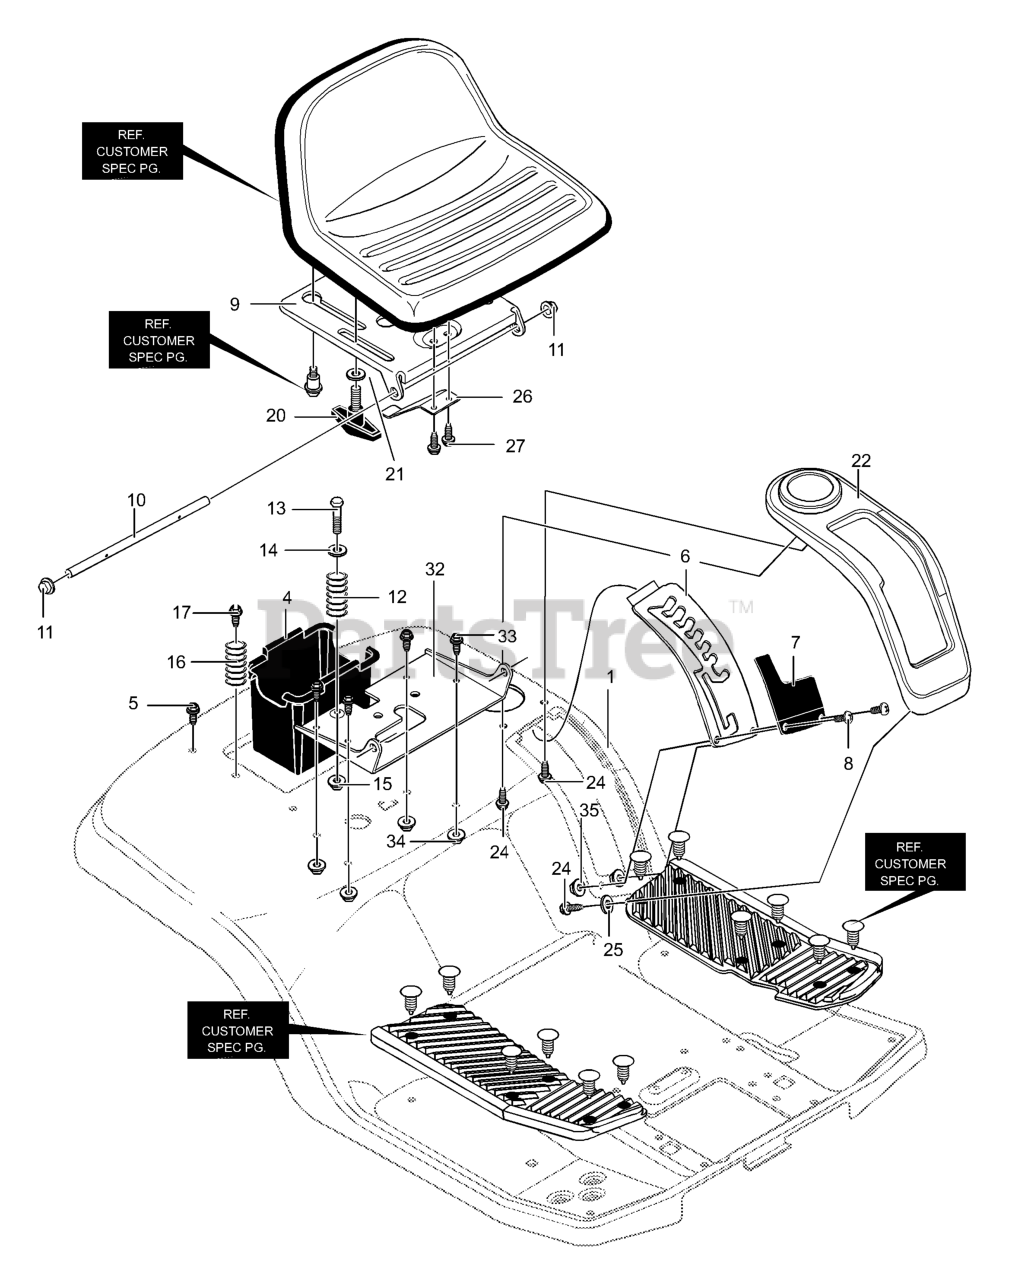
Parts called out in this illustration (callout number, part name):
1	SEAT DECK-LARGE
4	CONTAINER, BATTERY
5	SCREW, 1/4-20X .63
6	PLATE LIFT DETENT
7	LIFT DET LOCKOUT LG BLACK
9	SUPPORT, SEAT
10	HINGE SEAT PIVOT
11	NUT, PUSH CAP
12	SPRING, COMPRESSION
13	BOLT, SHOULDER
14	WASHER CUP
16	SPRING, COMPRESSION
20	BOLT, WING
21	WASHER, FLAT
22	DETENT COVER W/CUP
25	WASHER, FLAT
26	SPRING - LEAF
27	SCREW 5/16-18X.75
32	BRACKET, PIVOT SEAT
33	SCREW 5/16-18X.75
34	NUT, 5/16-18
35	NUT, #10-32
